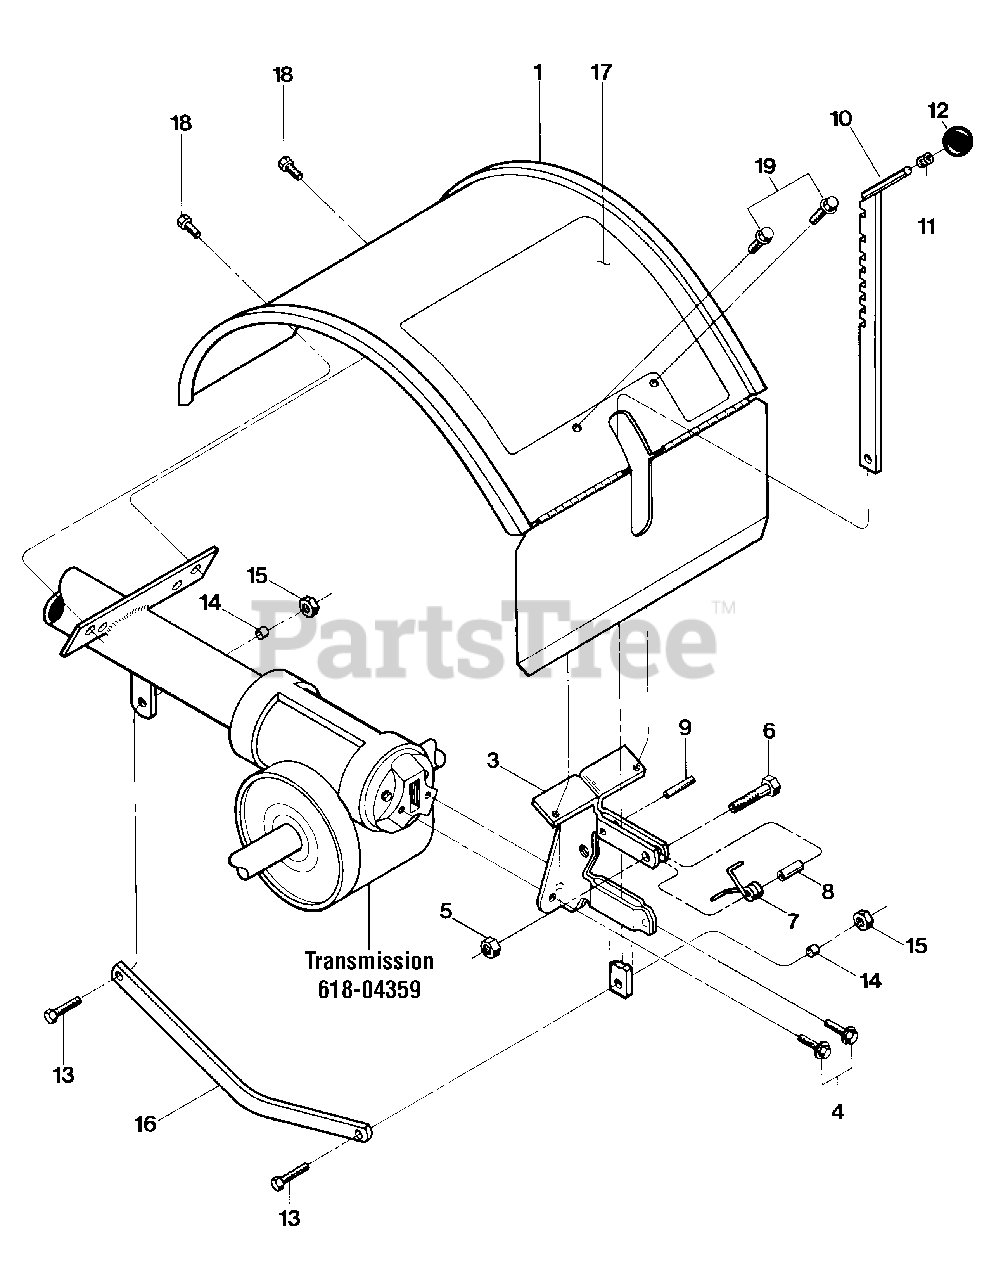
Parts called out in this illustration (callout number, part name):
3	Bracket-hood & depth regulator
4	Hex Flange screw 5/16-18 x 5/8
5	Hex Locknut, 1/4-20
6	Hex Hd. Screw, 1/4-20 x 1
9	Roll Pin (spiral), 1/4 x 1
10	Depth Adjustment Bar Assembly (Incl. Refs. 11 and 12)
11	Retaining Ring (tolerance ring)
12	Knob, Depth Regulator
13	Hex Hd. Screw, 3/8-16 x 1-1/4
14	Bushing, Drag Bar
15	Hex Nut, 3/8-16
16	Drag Bar
17	Decal, operating instructions
18	Hex Hd. Screw, self tapping 5/16-18 x 5/8
19	Hex Flange Screw, self tapping, 1/4-20 x 1/2
